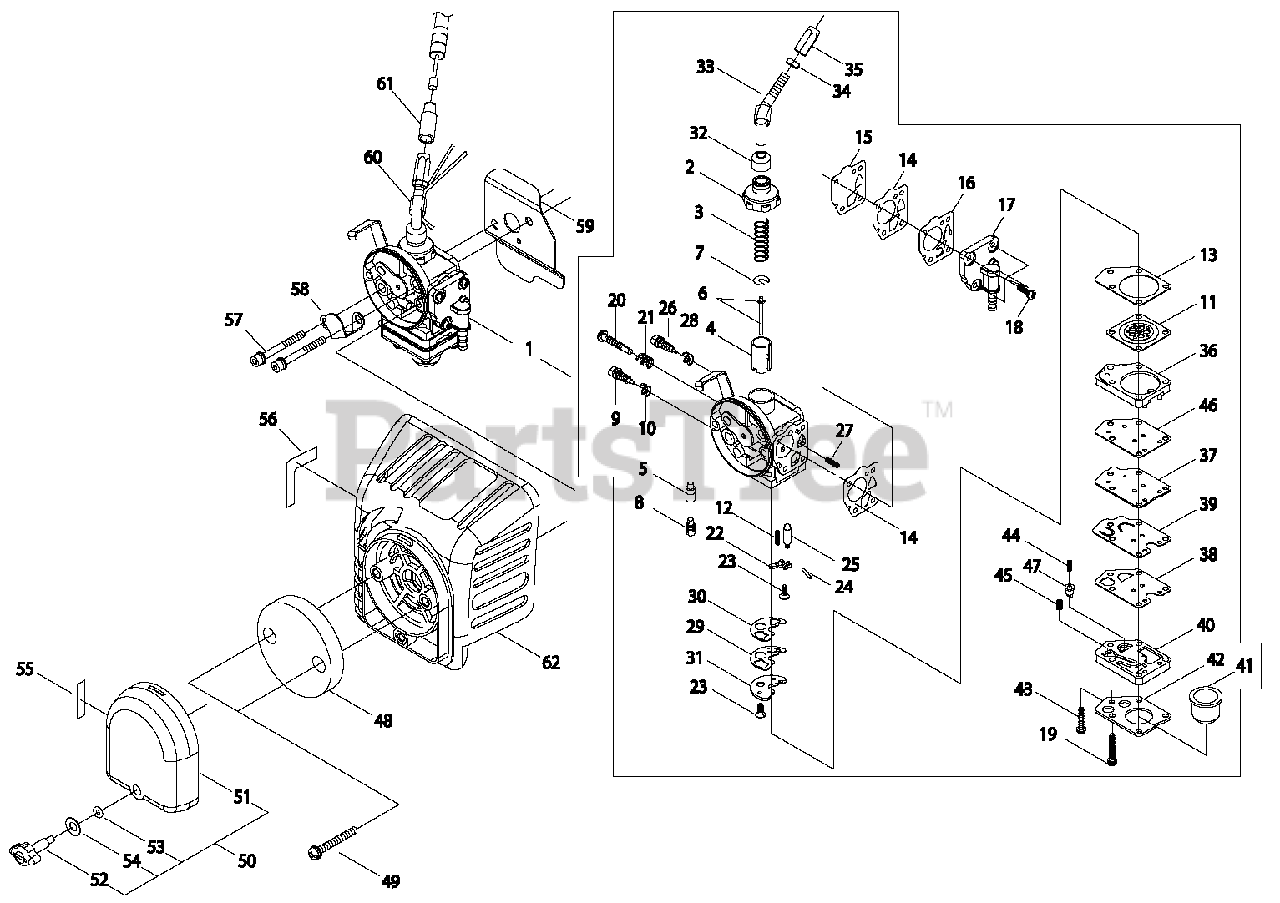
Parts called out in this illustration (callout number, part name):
1	CARBURETOR DPV11W-19A
2	CAP, CARBURETOR
3	SPRING, THROTTLE
3	NEEDLE, JET
4	VALVE, SLIDE
5	JET, MAIN
6	NEEDLE, JET
7	WASHER, SPRING SUPPORT
8	HOLDER, MAIN JET
9	SCREW, MAIN ADJUST
10	SPRING
11	DIAPHRAGM, METERING
12	SPRING
13	GASKET, METERING DIAPHRAGM
14	GASKET, DIAPHRAGM
15	DIAPHRAGM, METERING
16	VALVE, PUMP
17	PUMP BODY
18	SCREW
19	SCREW 3×20
20	SCREW, IDLE ADJUST
21	SPRING
22	LEVER, METERING
23	SCREW M3×8
24	PIN, METERING LEVER
25	VALVE, INLET NEEDLE
26	SCREW, SLOW AIR
27	SPRING
28	SPRING
29	VALVE, CHECK
30	PACKING
31	PLATE
32	CAP, DUST
33	PIPE, CABLE ADJUSTER
34	NUT, LOCK
35	ADJUSTER, CABLE
36	COVER, PUMP
37	GASKET
38	PLATE, PUMP
39	VALVE, CHECK
40	BODY, PURGE
41	BULB, PURGE
42	RETAINER, PURGE BULB
43	SCREW
44	SPRING
45	SPRING
46	GASKET
47	VALVE, CHECK
48	FILTER, AIR
49	SCREW M4×25
50	COVER ASSY, AIR FILTER
51	COVER, AIR FILTER
52	THUMBSCREW
53	O-RING
54	WASHER, CONE M6
55	LABEL, CHOKE
56	LABEL, CARBURETOR
57	BOLT
58	PLATE
59	GASKET, CARBURETOR
60	TUBE, PROTECTIVE
61	CAP, CARBURETOR
62	CASE, AIR FILTER
